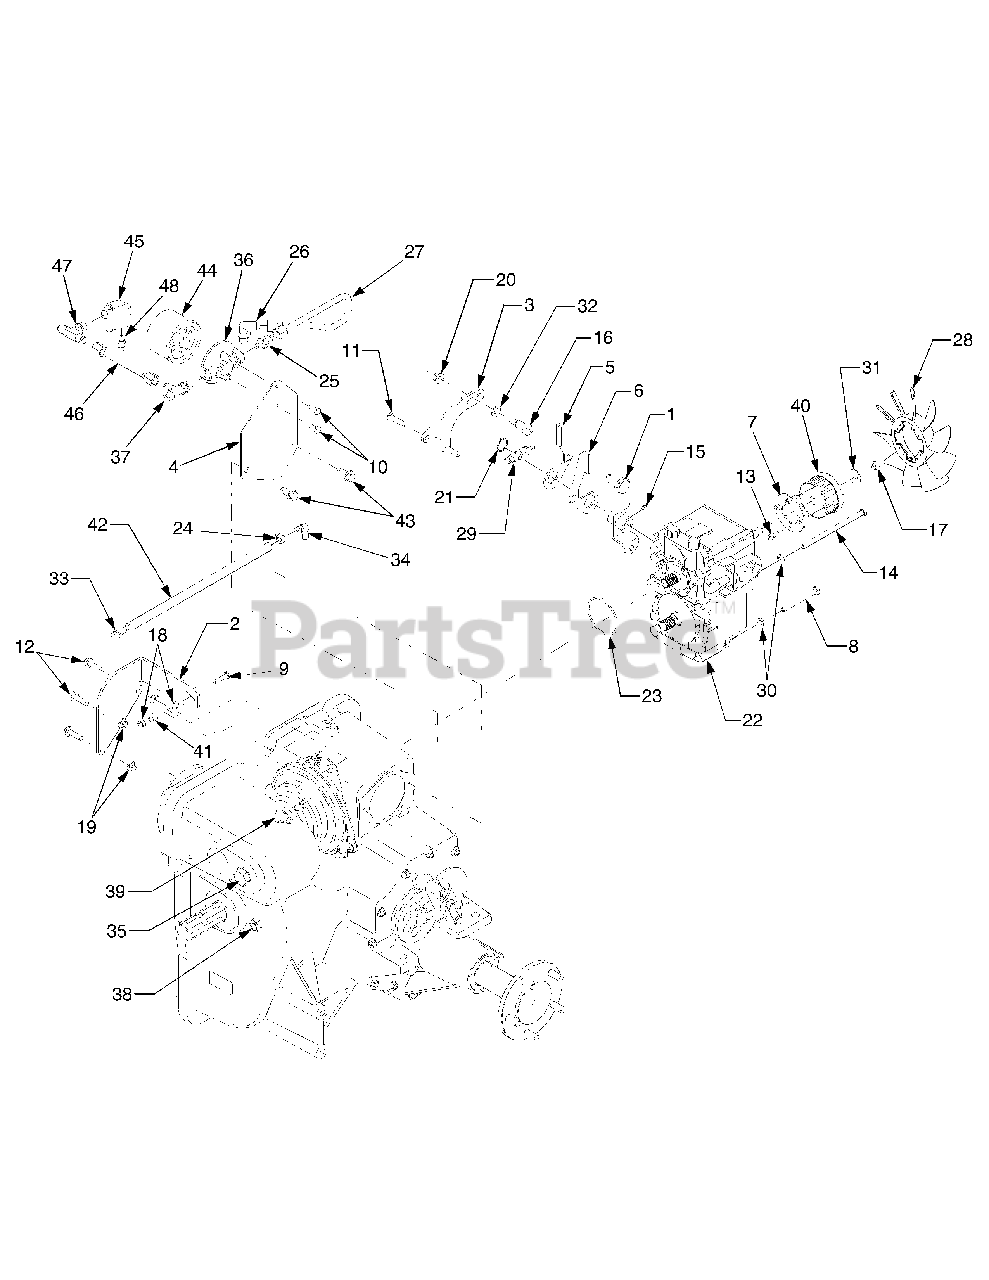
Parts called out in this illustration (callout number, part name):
1	Arm, Hydro
2	Bracket, Clutch Torque
3	Bracket, Return
4	Bracket, Filter Mounting
5	Arm, Neutral - RH
6	Arm, Neutral - LH
7	Keeper, Belt
8	Screw, Hex Cap, 5/16-18 x 3.0 GR5
9	Screw, Hex Cap, 1/4-28 x 1.0 GR5
10	Screw, Hex Cap, 1/4-20 x .62 GR5
11	Screw, Hex Wash. Hd. Tapp, 5/16-18 x 1.25 GR5
12	Screw, Hex Flange, 5/16-18 x 1.5 GR5
13	Screw, Socket Hd. Cap 1/4-20 x .62 GR8
14	Screw, Hex Cap Lock, 5/16-18 x 5.5 GR5
15	Screw, Set - Lock 5/16 x .5 GR5
16	Screw, Shoulder, .497 x .750: 3/8-16
17	Nut, Hex Jam Lock, 3/8-24
18	Nut, Hex Nylon Lock, 1/4-28
19	Nut, Hex Flange Lock, 5/16-18 GR5
20	Nut, Hex Flange Lock, 3/8-16
21	Ring, Retaining
22	Pump, Hydrostatic Transmission
23	O-Ring, 2.425 ID x .103
24	Clamp, Hose
25	Fitting, Straight
26	Fitting, 90 Degree
27	Tube, Hydro Inlet
28	Fan, Transmission Cooling
29	Spring, Extension, .50 x 1.975 x.072
30	Washer, Lock, 5/16
31	Washer, Belleville
32	Washer, Thrust, .375 x .812 x .06
33	Vent, 3/8 Dia
34	Fitting, Elbow
35	Fitting, Plug
36	Adapter, Oil Filter
37	Fitting, Run Tee
38	Indicator, Oil Level Sight
39	Fitting, Elbow
40	Adapter. Cog Pump
41	Tube, Rubber, .25 .375 x .38
42	Hose, Vent
43	Screw, Hex Wash Hd Tapp 3/8-16 x .62
44	Filter, Hydro Pump
45	Valve, Check, 30 PSI
46	Tube, Inlet Filter
47	Fitting, Branch Tee
48	Fitting, Adapter
